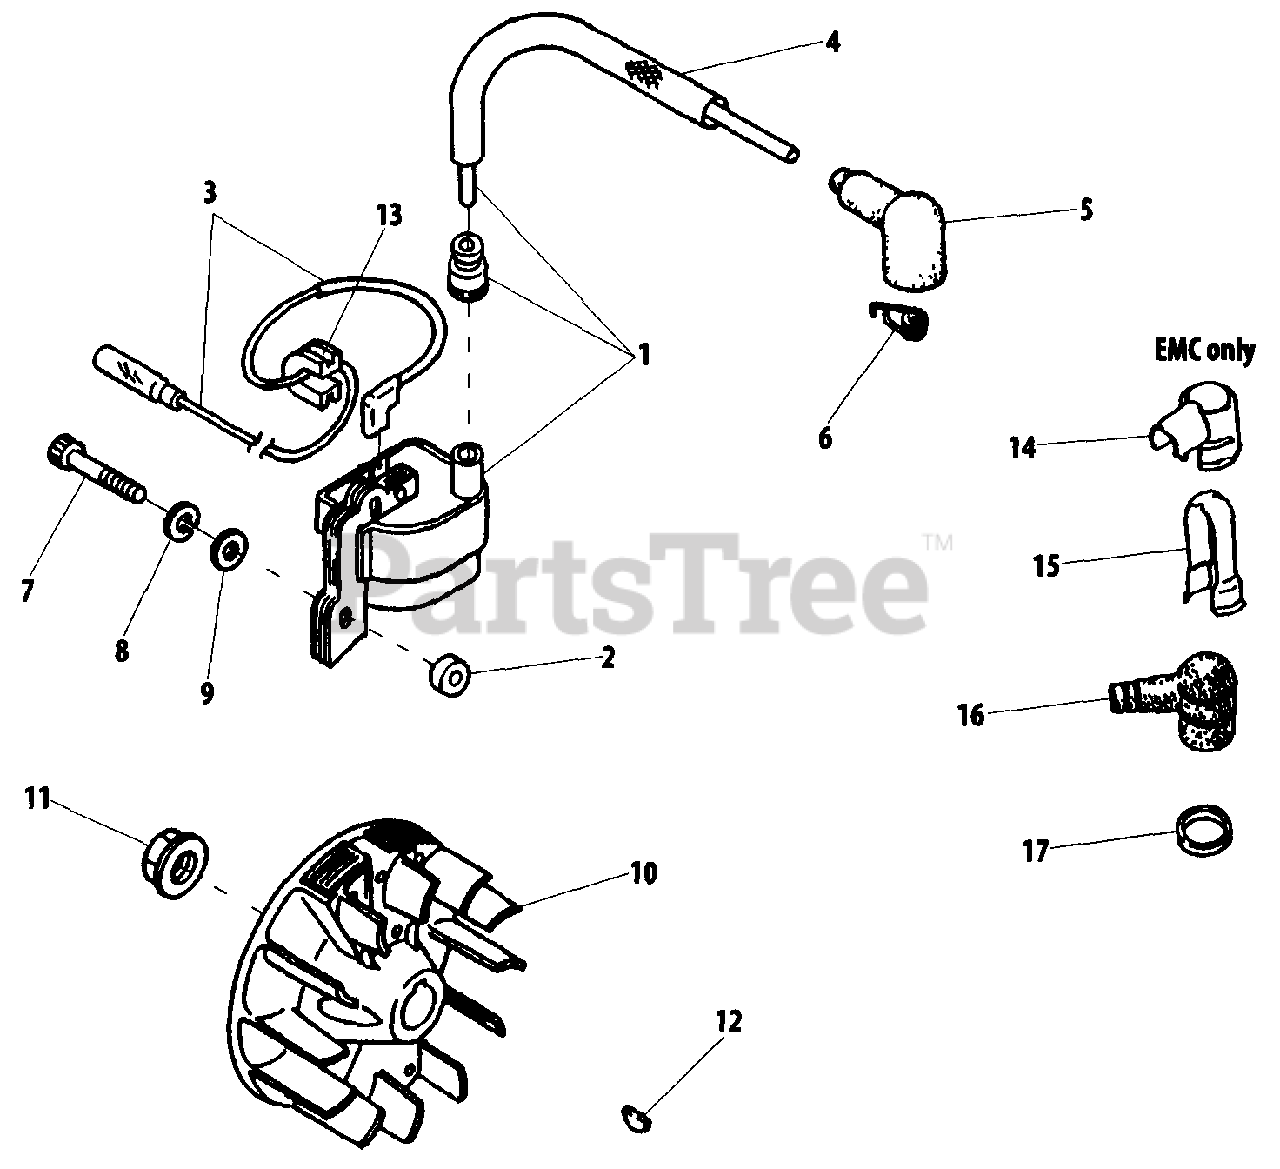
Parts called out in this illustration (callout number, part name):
1	COIL ASSY, IGNITION
2	INSULATOR 4.2×11×6
3	LEAD - IGNITION
4	TUBE, INSULATOR
5	CAP, SPARK PLUG
6	TERMINAL, SPARK PLUG
7	BOLT
8	WASHER, SPRING 4 MM
9	WASHER 4 MM
10	FLYWHEEL
11	NUT M8
12	KEY, WOODRUFF 3×10
13	GROMMET, LEAD
14	COVER, CAP
15	SHIELD
16	CAP, SPARK PLUG
17	SEAL, SPARK PLUG
